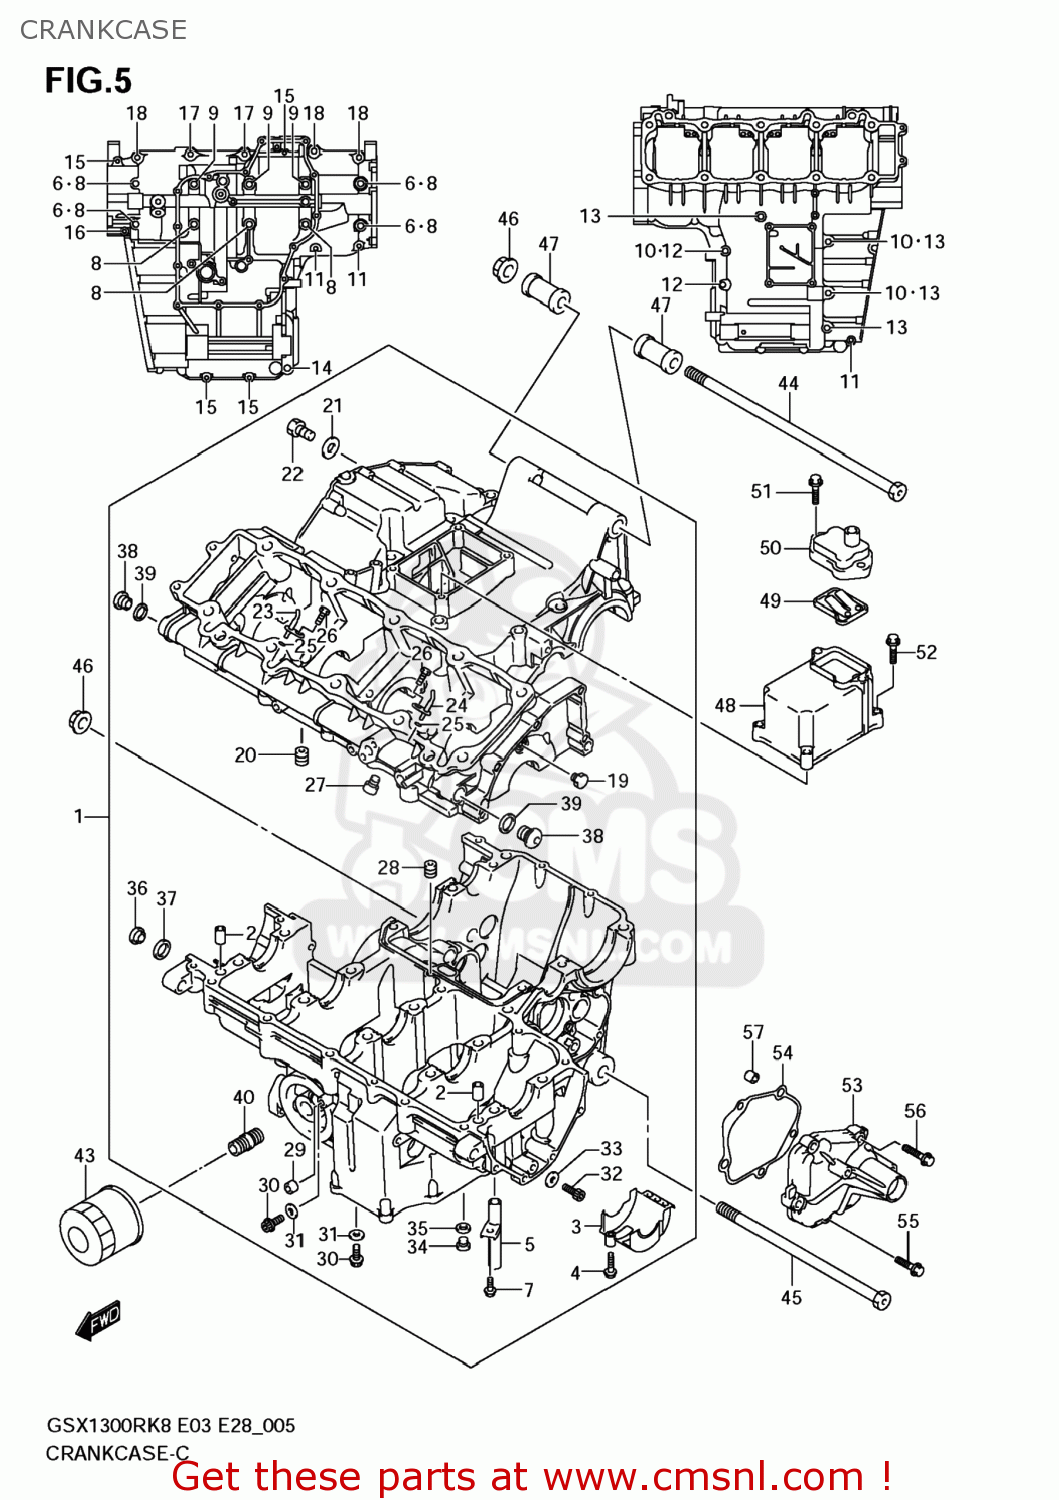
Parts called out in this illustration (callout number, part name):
1	CRANKCASE SET
2	PIN,CRANKCASE
3	SEPARATOR,OIL
4	BOLT
5	UNION,BREATHER
6	GASKET(10.2X20X2).3 (NAS)
7	BOLT
8	BOLT(9X95)
9	BOLT(9X115)
10	GASKET(8.2X14X1) (NAS)
11	BOLT
12	BOLT
13	BOLT
14	BOLT
15	BOLT
16	BOLT
17	BOLT(8X60)
18	BOLT(8X50)
19	JET,MAGNETO COOLING
20	JET,AIR(100)
21	GASKET(5.8X13X1.2) (NAS)
22	BOLT
23	JET,PISTON COOLINGR
24	JET,PISTON COOLING
25	O RING(D:1.2,ID:4)
26	BOLT(6X12)
27	BOLT(6X10)
28	JET,AIR(180)
29	JET,OIL PAN GALLERY
30	BOLT
31	GASKET(5.8X13X1.2) (NAS)
32	BOLT
33	GASKET(8.2X14X1) (NAS)
34	PLUG(10X10)
35	GASKET(10X14X3.6) (NAS)
36	PLUG,16X8
37	GASKET(16X22X2) (NAS)
38	PLUG,14X12
39	GASKET(13.8X18.8X4.8) (NAS)
40	UNION,OIL STAND
41	BEARING,CRANK THRUST,L
42	BEARING,CRANK THRUST,L
43	FILTER ASSY,EN
44	BOLT(12X320)
45	BOLT(12X243)
46	NUT
47	SPACER,ENG MTG(L47)
48	COVER,BREATHER
49	VALVE ASSY,BRE
50	COVER,BREATHER REED VALVE
51	BOLT
52	BOLT
53	COVER,GEAR SHIFT
54	GASKET,GEAR SHIFT COVER (NAS)
55	BOLT
56	BOLT
57	PIN
